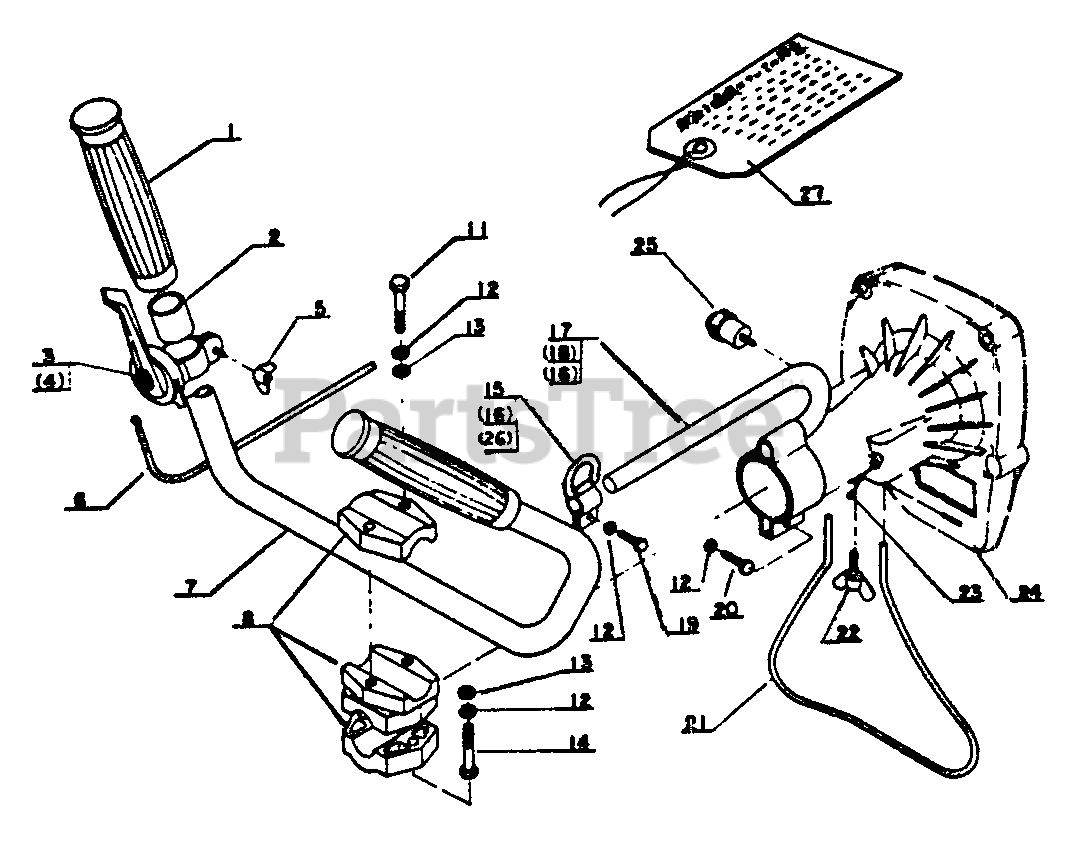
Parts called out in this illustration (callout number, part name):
1	GRIP, HANDLE
2	Rubber band
3	LEVER, THROTTLE
5	NUT - BUTTERFLY
6	CABLE, THROTTLE
8	Handle set plate
11	BOLT - 6X25
12	LOCKWASHER - 6
13	WASHER - 6
14	BOLT - 6X30
15	HANGER, BAND
17	HOLDER, BAND HANGER
19	BOLT - 6X14
20	BOLT - 6X18
23	PLUG, FAN COVER
24	PIN - SPRING -- 3X12
25	BUTTON, STOP
27	LABEL - CAUTION
